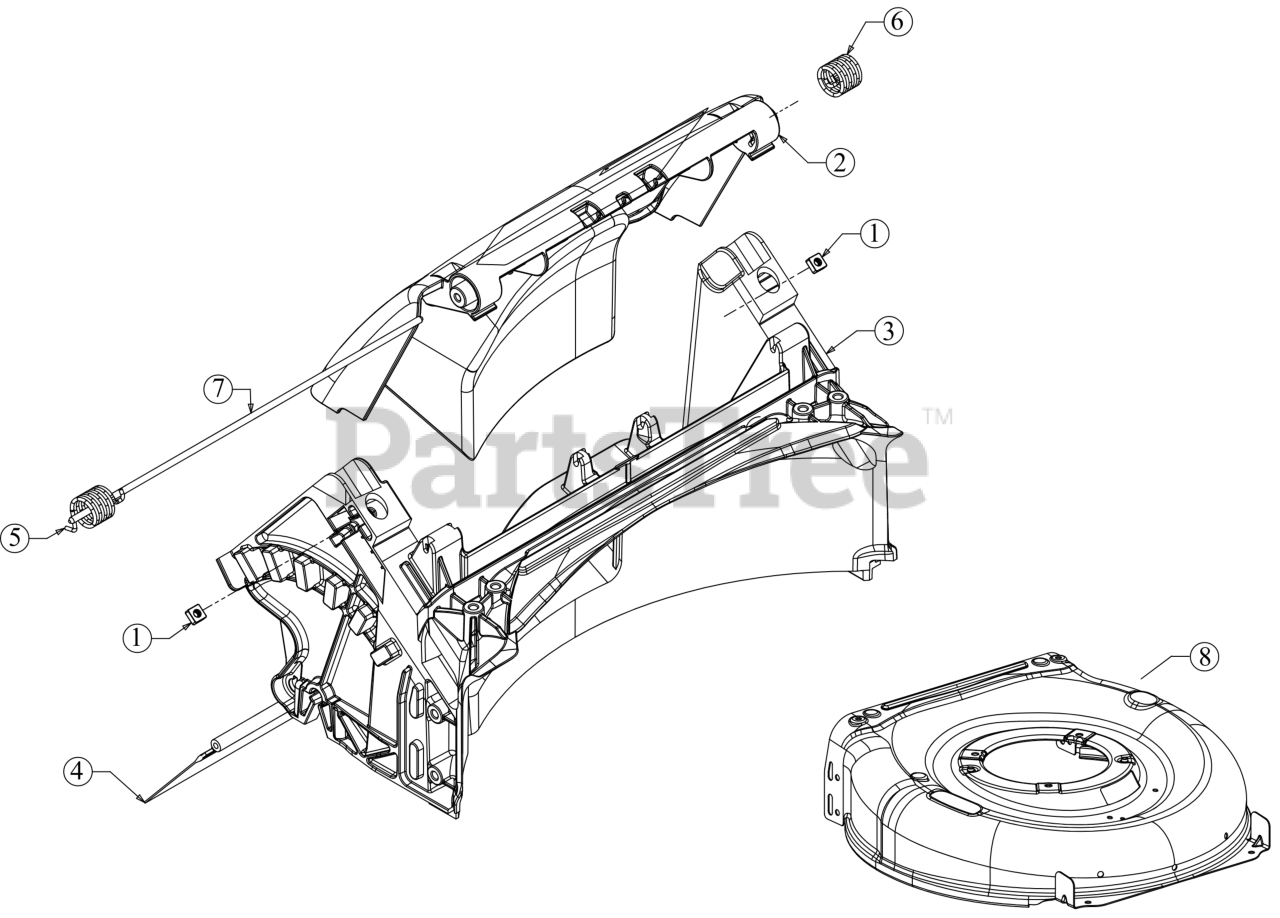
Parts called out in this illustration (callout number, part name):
1	SQUARE NUT 1/4-20
3	DOOR ASSEMBLY
4	TRAILSHIELD
5	TORSION SPRING (RH)
6	TORSION SPRING (LH)
7	REAR DOOR PIVOT ROD
